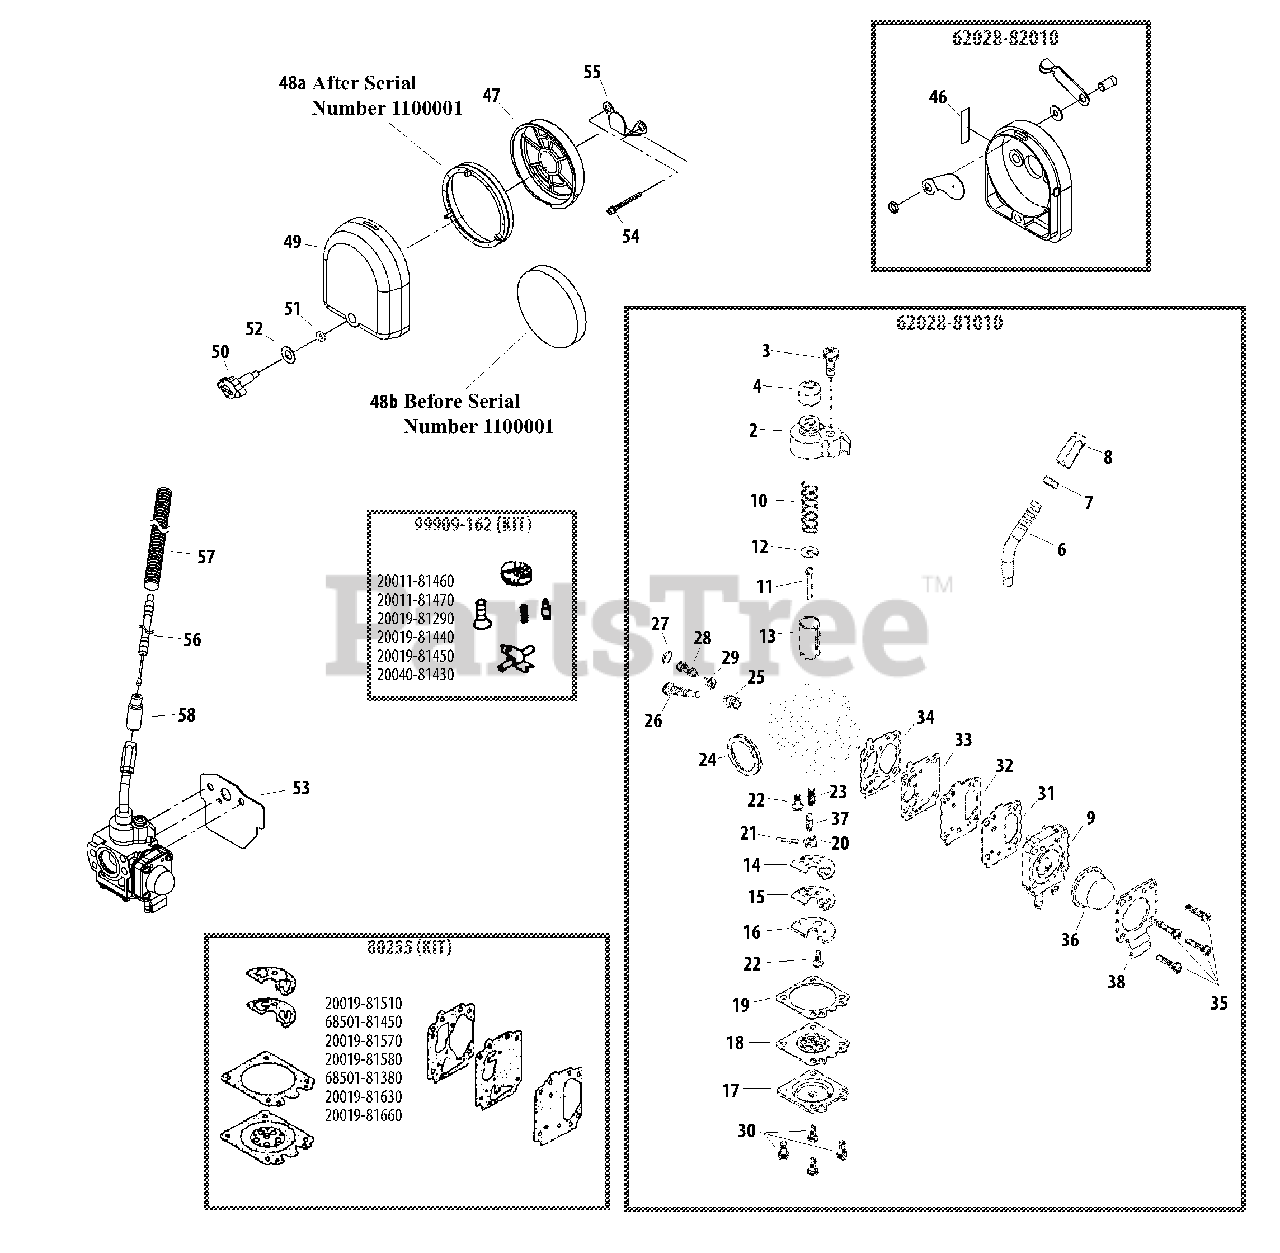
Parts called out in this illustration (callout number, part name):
2	CAP, CARBURETOR
3	SCREW M5×15
4	CAP, DUST
6	TUBE, ADJUST
7	NUT, LOCK
8	ADJUSTER, CABLE
9	COVER ASSY, PUMP
10	SPRING, THROTTLE
11	NEEDLE, JET
12	WASHER, SPRING SUPPORT
13	VALVE, THROTTLE
14	GASKET
15	VALVE, CHECK
16	PLATE
17	COVER, DIAPHRAGM
18	DIAPHRAGM, METERING
19	GASKET, METERING DIAPHRAGM
20	LEVER, METERING
21	PIN, METERING LEVER
22	SCREW M3×8
23	SPRING
24	RING, PACKING
25	SPRING
26	SCREW, IDLE ADJUST
27	PLATE
28	SCREW, MAIN ADJUST
30	SCREW M3×8
31	GASKET, FUEL PUMP
32	PLATE, PUMP
33	DIAPHRAGM, FUEL PUMP
34	GASKET, PUMP
35	SCREW M3×14
36	BULB, PURGE
37	VALVE, INLET NEEDLE
38	COVER, PUMP
46	LABEL, CHOKE
47	SCREEN, REAR AIR FILTER
48A	FILTER, HEAVY-DUTY AIR
48B	FILTER, AIR
49	COVER, AIR FILTER
50	THUMBSCREW
51	O-RING
52	WASHER, CONE M6
53	GASKET, CARBURETOR
54	BOLT M5×50
55	PLATE
56	CABLE, THROTTLE
57	TUBE, PLASTIC PROTECTIVE
58	CAP, CARBURETOR
20019-81290	SCREEN, FUEL INLET
62028-81010	CARBURETOR
62028-82010	CASE ASSY, AIR FILTER
80255	GASKET / DIAPHRAGM KIT
99909-162	REPAIR KIT
